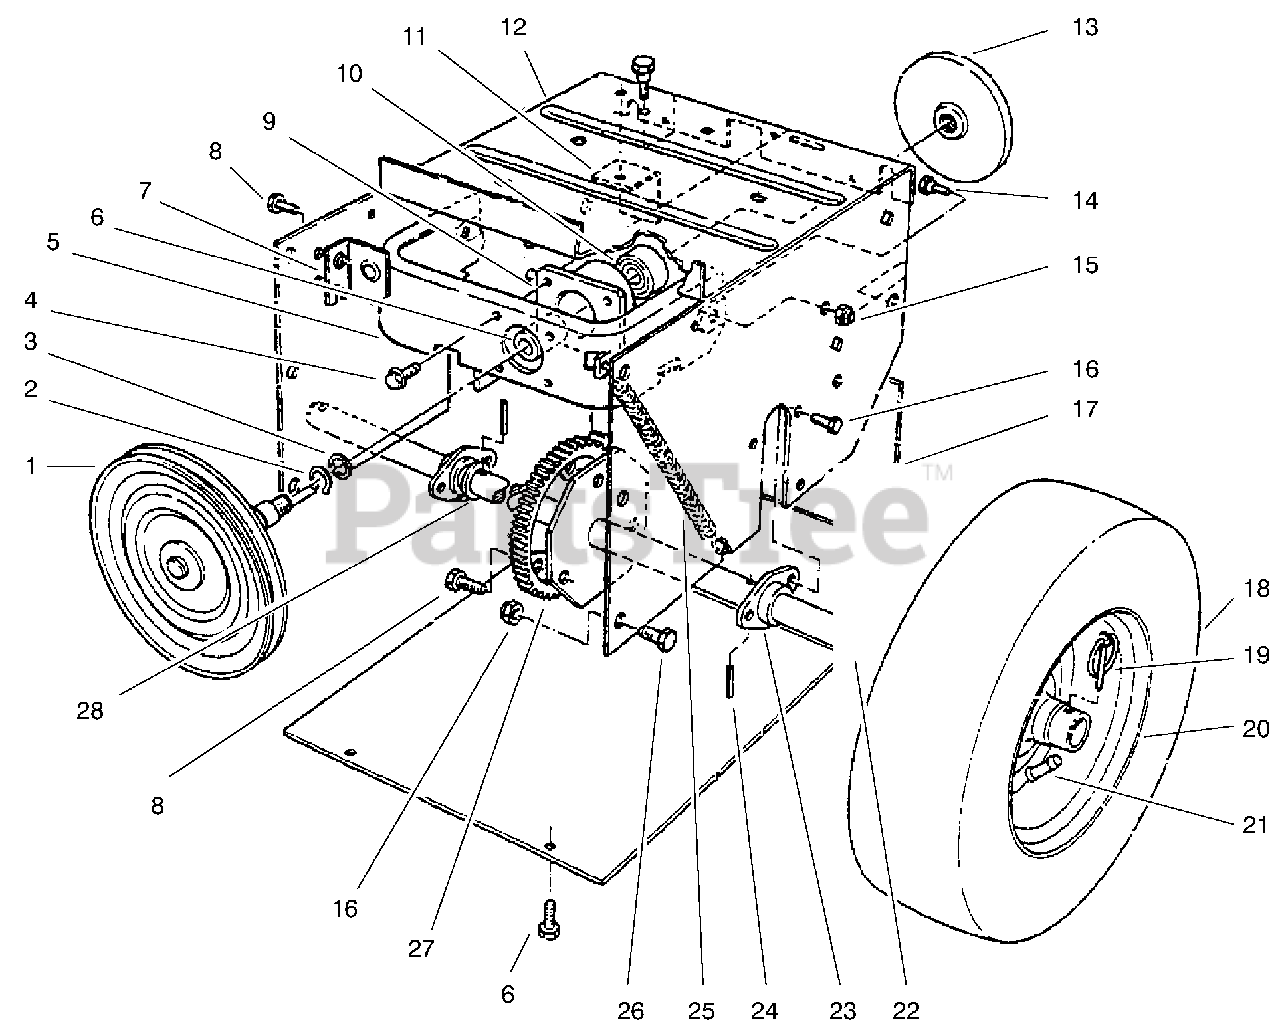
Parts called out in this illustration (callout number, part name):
1	PULLEY & DRIVE ASM
2	RING-SNAP
3	WASHER-THRUST
5	Frame-Friction Plate
7	BRACKET-MOUNT CLUTCH, FRONT
9	HUB-FRAME, TRACTION
10	BEARING-BALL
11	BRACKET-MOUNT CLUTCH, REAR
12	FRAME-TRACTION
13	PLATE-FRICTION
14	BOLT-SHOULDER
15	NUT-LOCK, NI
16	SCREW-HWH
17	COVER-TRACTION, LOWER
19	PIN-LYNCH
20	RIM-WHEEL
22	SHAFT-AXLE
23	BEARING-AXLE
24	PIN-SPRING
25	SPRING-PLATE,FRICTION
26	SCREW-HH
27	GEAR-AXLE
28	WASHER-THRUST
